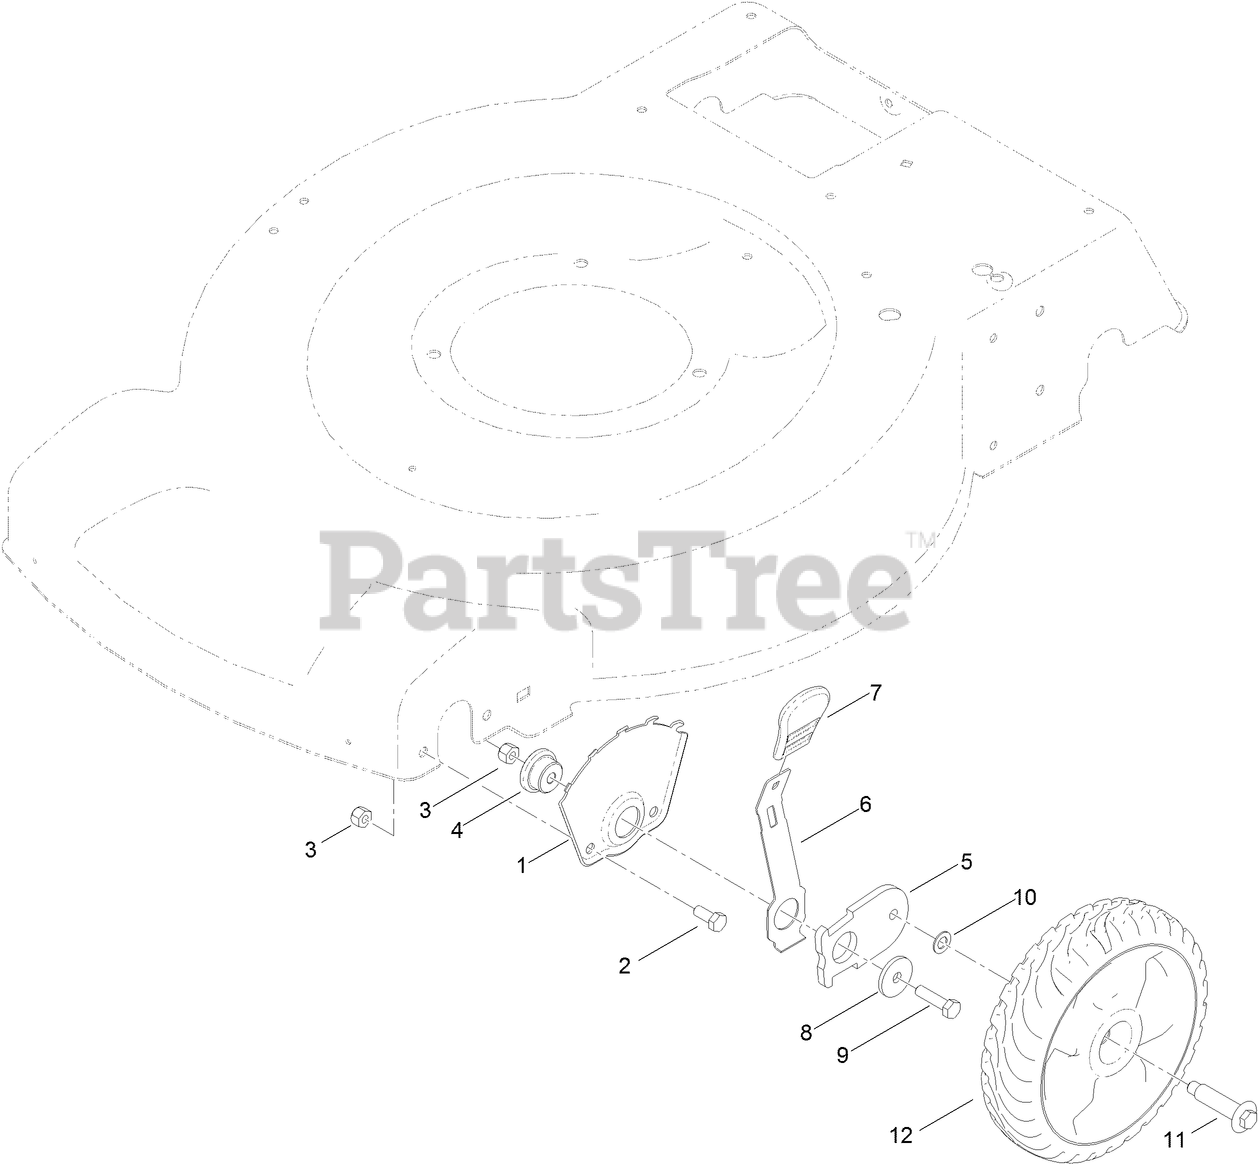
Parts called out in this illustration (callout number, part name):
1	PLATE-HOC, FRONT
2	SCREW-HH
3	NUT-LOCK, NI
4	BUSHING-MOUNT, HOC
6	ARM-SPRING
7	KNOB-HOC
8	WASHER-FLAT
9	SCREW-HH
10	WASHER
11	BOLT-SHOULDER
